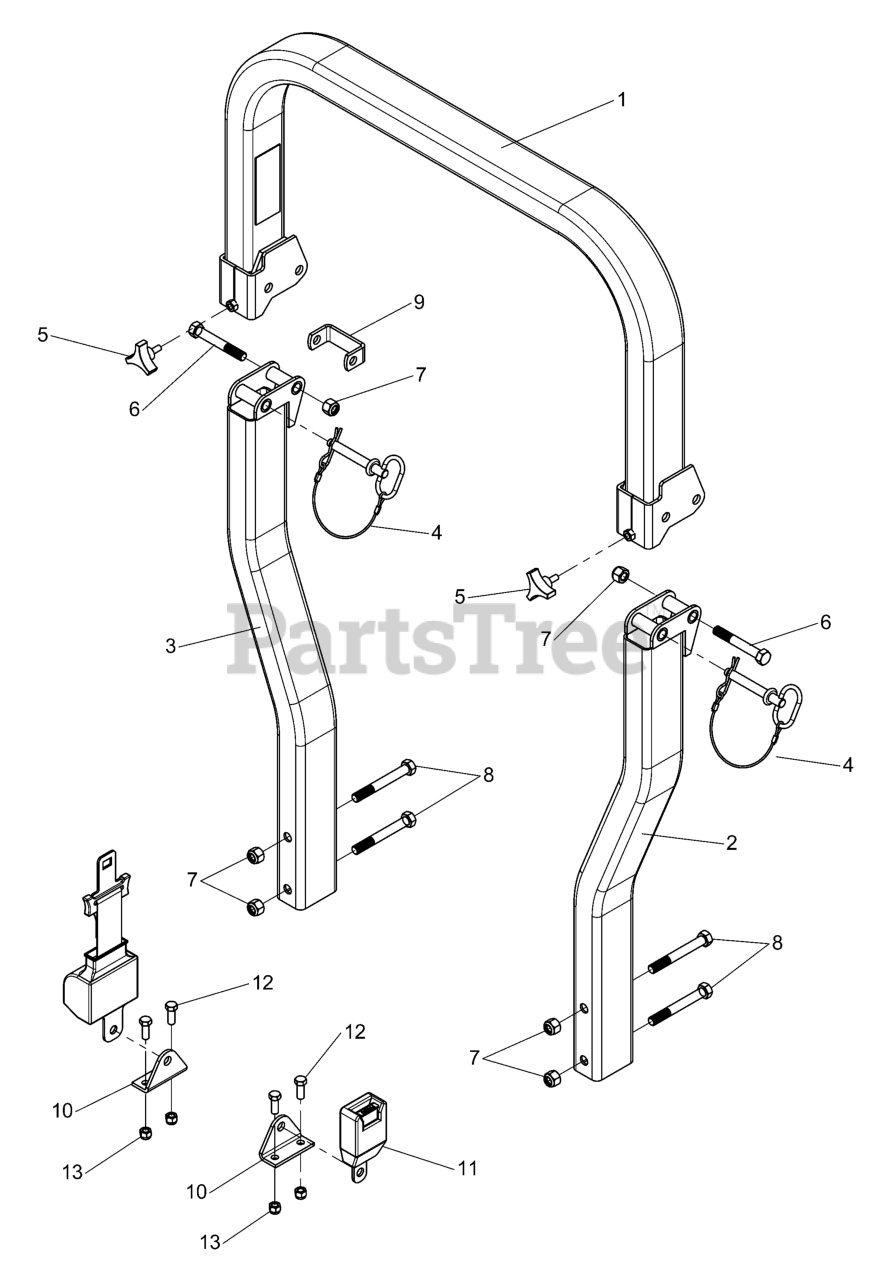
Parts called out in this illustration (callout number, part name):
1	ROPS TOP LOOP
2	ROPS POST, LH
3	ROPS POST, RH
4	PIN, HITCH, .50 X 3.25 W/ LANYARD
5	KNOB, PLASTIC, 5/16-18 X 3/4"
6	BOLT, 1/2-13 X 3-1/2, HEX HD, GD5, CZ (SV)
7	NUT, 1/2-13 HEX NYLON LOCK
8	BOLT, 1/2-13 X 4" GD5 CZ
9	ROPS, STOP - IS4500
10	MOUNT, SEAT BELT - IS4500
11	SEAT BELT, COMPLETE W/ HARDWARE
12	BOLT, 3/8-16 X 1" GD5 CZ
13	NUT, 3/8-16 HEX NYLON LOCK
